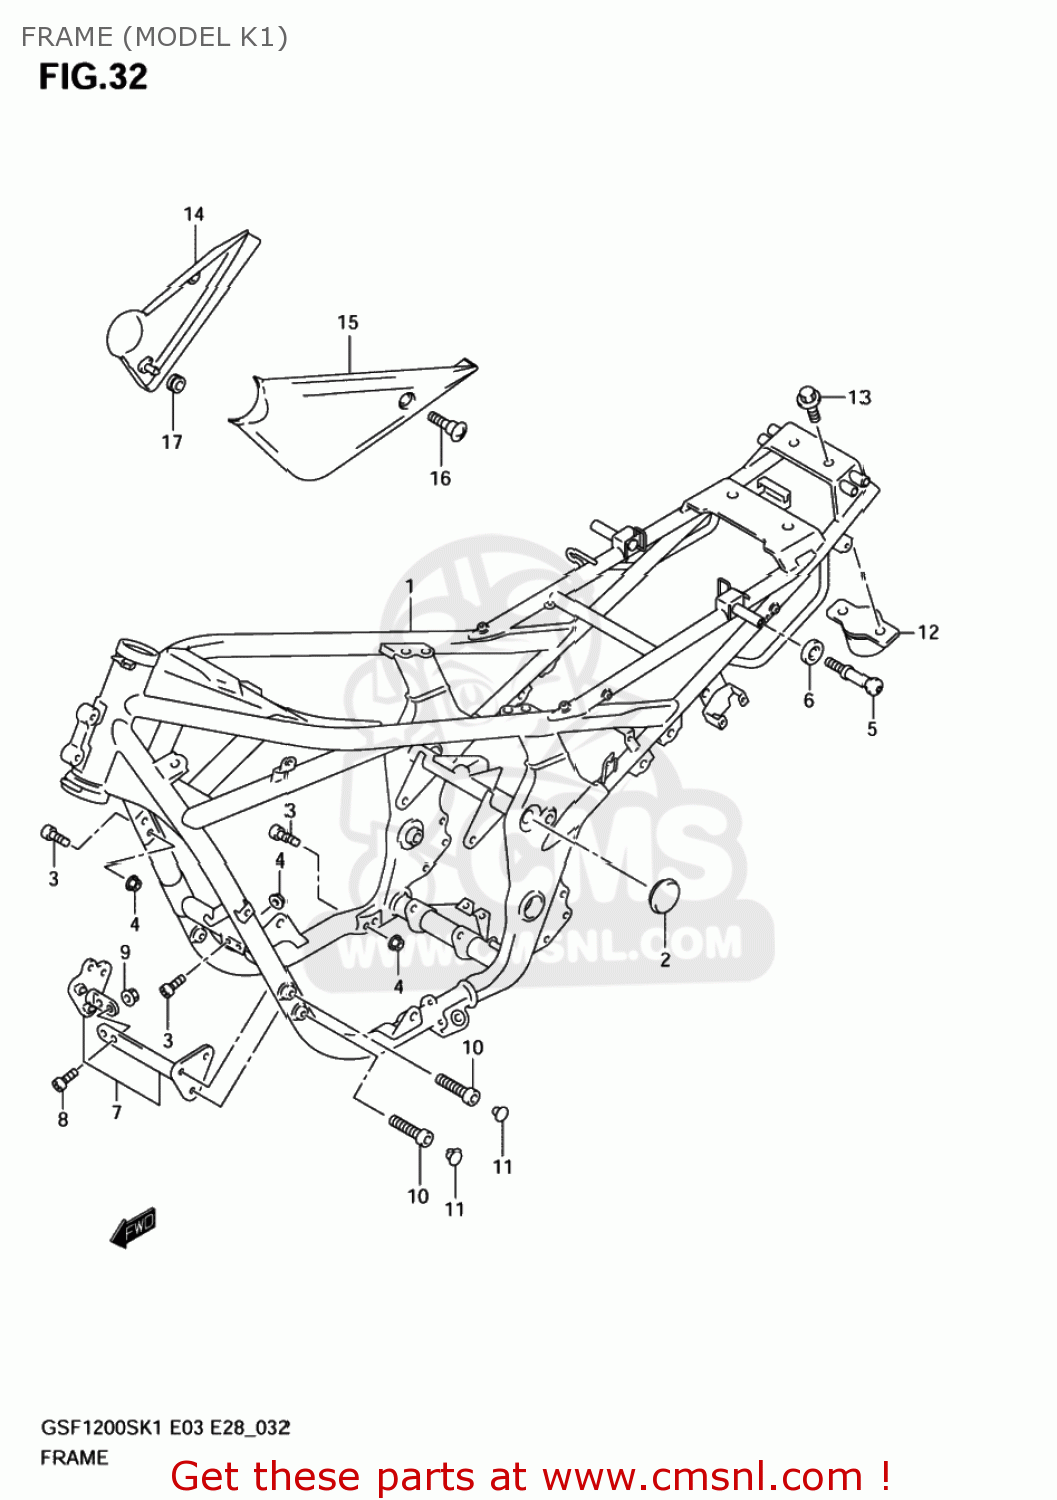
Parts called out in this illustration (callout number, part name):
1	FRAME (RED)
2	CAP,FRAME BODY
3	BOLT(10X37)
4	NUT
5	HOOK,SEAT RAIL
6	WASHER,HOOK
7	PLATE,ENGINE MOUNT NO.1
8	BOLT
9	NUT
10	BOLT
11	CAP(OD:12)
12	DAMPER,FRAME RR
13	BOLT
14	COVER,FRAME HEAD,R
15	COVER,FRAME HEAD,L
16	SCREW(5X12)
17	CUSHION
